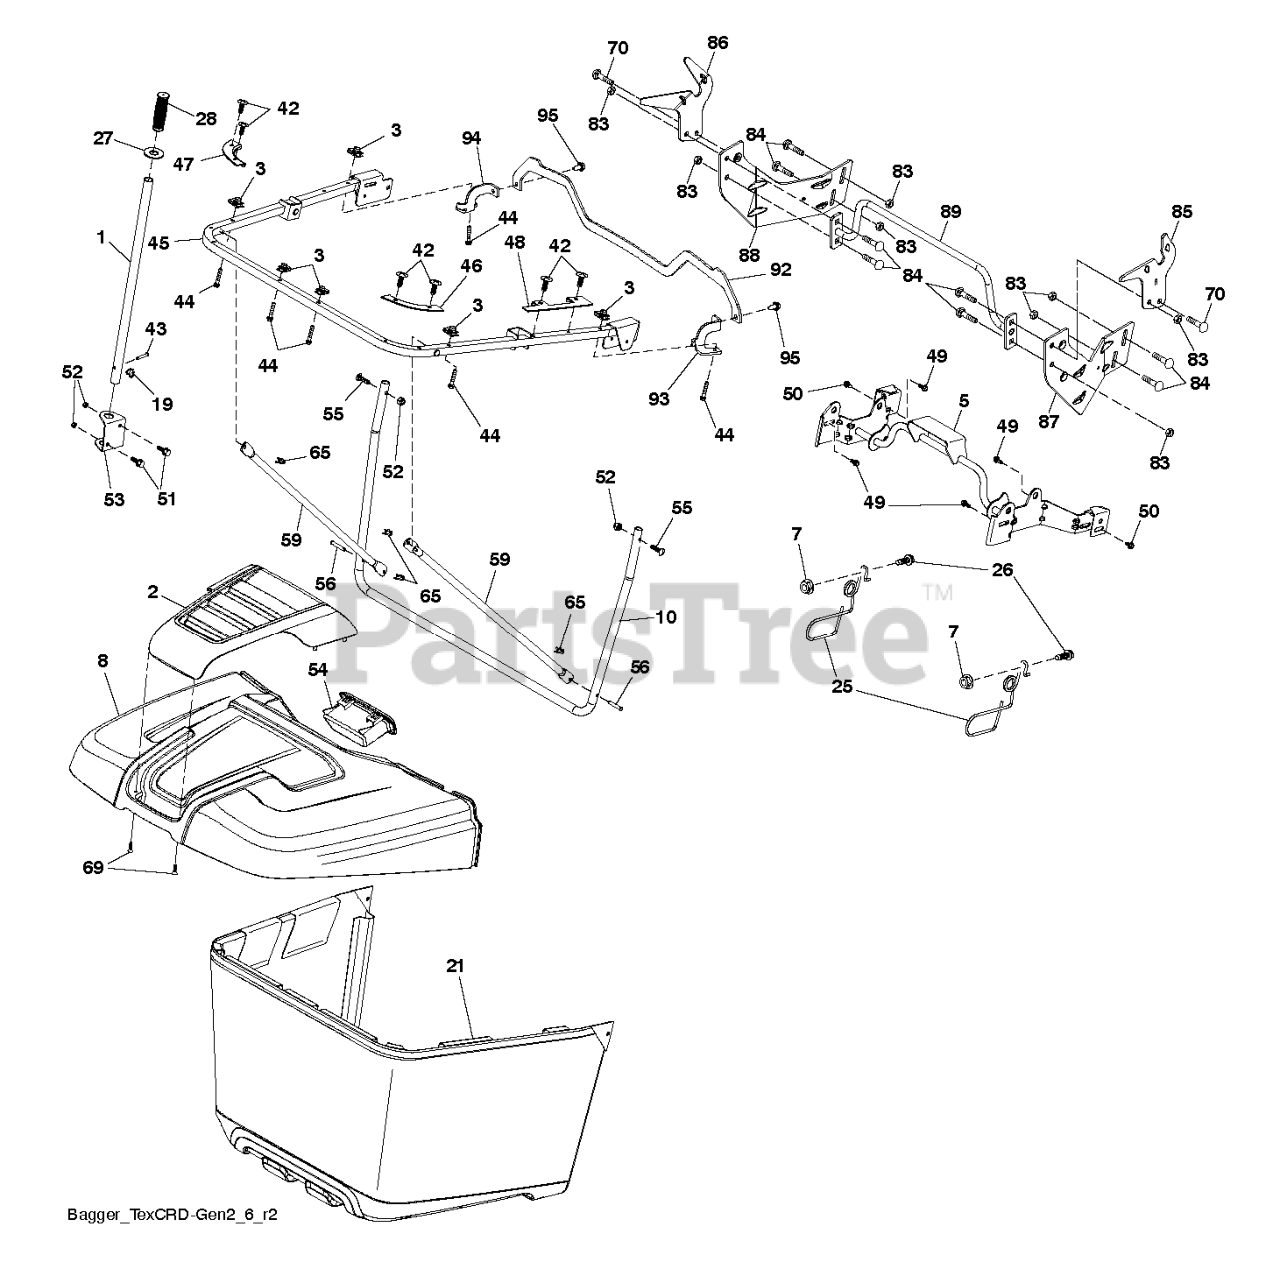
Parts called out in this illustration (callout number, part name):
1	TUBE.HANDLE.BAGGER.CRD/SRD.BLA
2	APPLIQUE.BAGGER
3	1/4-20 U NUT
5	FRAME TEX_CRD_GEN2 UPPER PIVOT
7	NUT T
8	BAGGER TOP
10	FRAME TEX_CRD_GEN2 BAGGER FRAM
19	PIN.COTTER.5/16.BOW TI
21	BAGGER.ASM.FABRIC.CRD.GII.HUSQ
25	LATCH LATCH. BAG. CRD GEN 2
26	SCREW HEX CRT
27	GROMMET RUBBER GROMMET, DUMP T
28	GRIP.HANDLE.BLACK
42	CLIP CHRISTMAS TREE CLIP
43	RIVET,DRILLED
45	FRAME TEX_CRD_GEN2 UPPER U FRA
46	CONNECTOR RIGHT BAGGER CORNER
47	CONNECTOR LEFT BAGGER CORNER C
48	BAFFLE BAGGER SIDE CLOSE-OUT
49	BOLT, SHOULDER 5/16-18
50	BOLT.5/16-18UNCX3/4 W/SEMS.BLK
51	BOLT.CARR.SQNK.5/16-18UNC.X3/4
52	NUT.71038.31-18.HEX.NYLOCK
53	BRACKET DUMP HANDLE BRACKET, T
54	HANDLE BAGGER TOP FRONT HANDLE
55	BOLT
56	PIN.CLEVIS.183
59	TUBE BAGGER SPREADER TUBE, TEX
65	RETAINER M
69	SCREW,#8.FLAT.HEAD.DRILL.TIP
70	SCREW, 3/8-16X3/4
83	NUT
84	BOLT D
85	BRACKET.RH.PIVOT.MAN.DUMP.BLAC
86	BRACKET.LH.PIVOT.MAN.DUMP.BLAC
87	BRACKET.RH.MID.SUP.BAG.TEX.CRD
88	BRACKET.LH.MID.SUP.BAG.TEX.CRD
89	TUBE.WELD.OFSET.STRUT.BAG.X431
92	BRACKET.PNT.BAGGER.TOP.SUPPORT
93	BRACKET.PNT.RH.SUPPORT.ATTACH
94	BRACKET.PNT.LH.SUPPORT.ATTACH
95	SCREW
